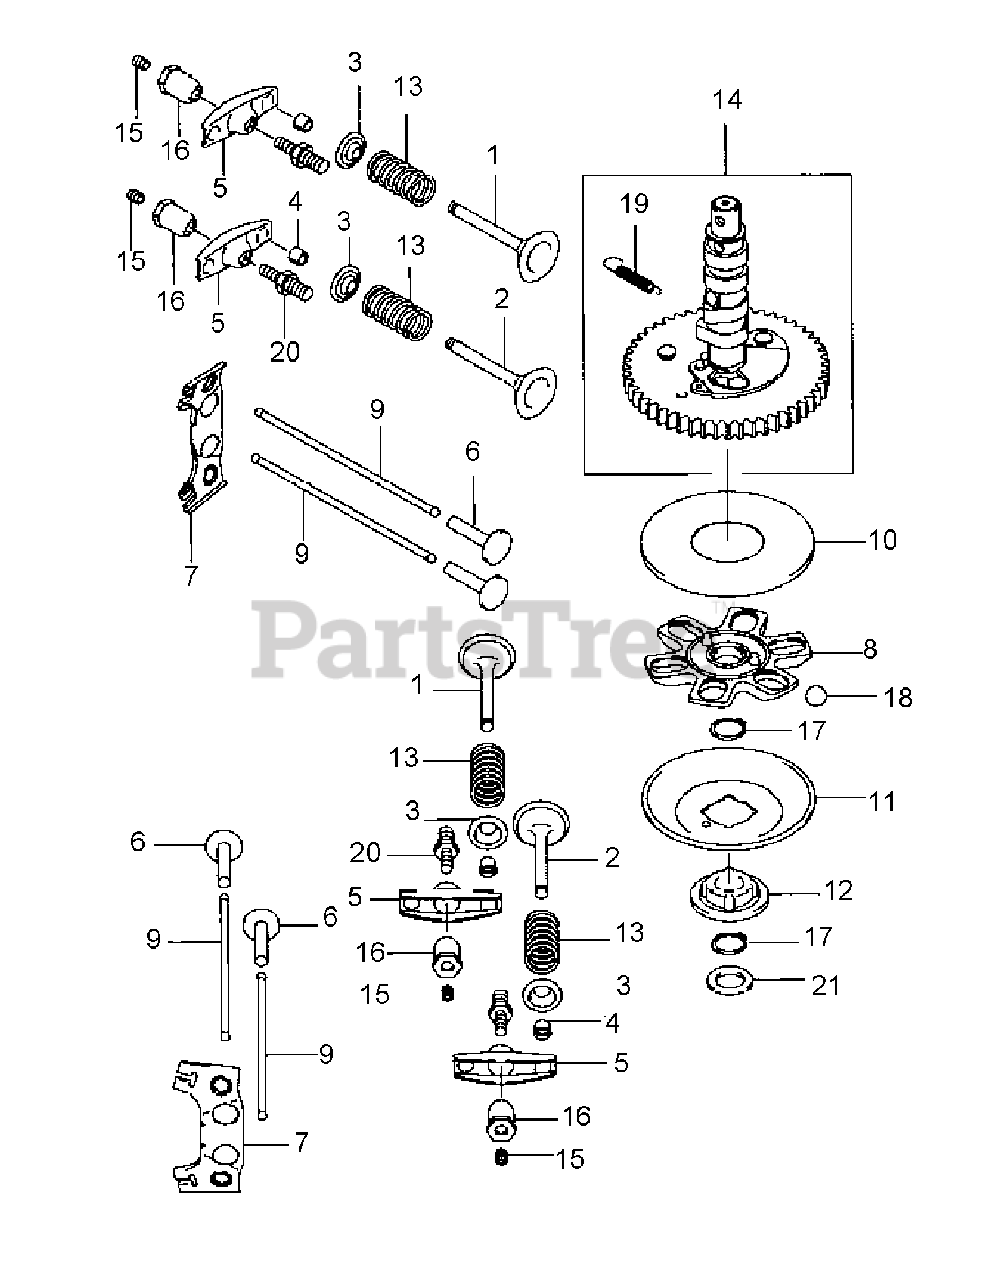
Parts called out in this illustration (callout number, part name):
1	VALVE-INTAKE
2	VALVE-EXHAUST
3	RETAINER-VALVE SPRING
11	PLATE, GOVERNOR
13	SPRING-ENGINE VALVE
14	CAMSHAFT-COMP
17	RING-SNAP
18	BALL
19	SPRING
